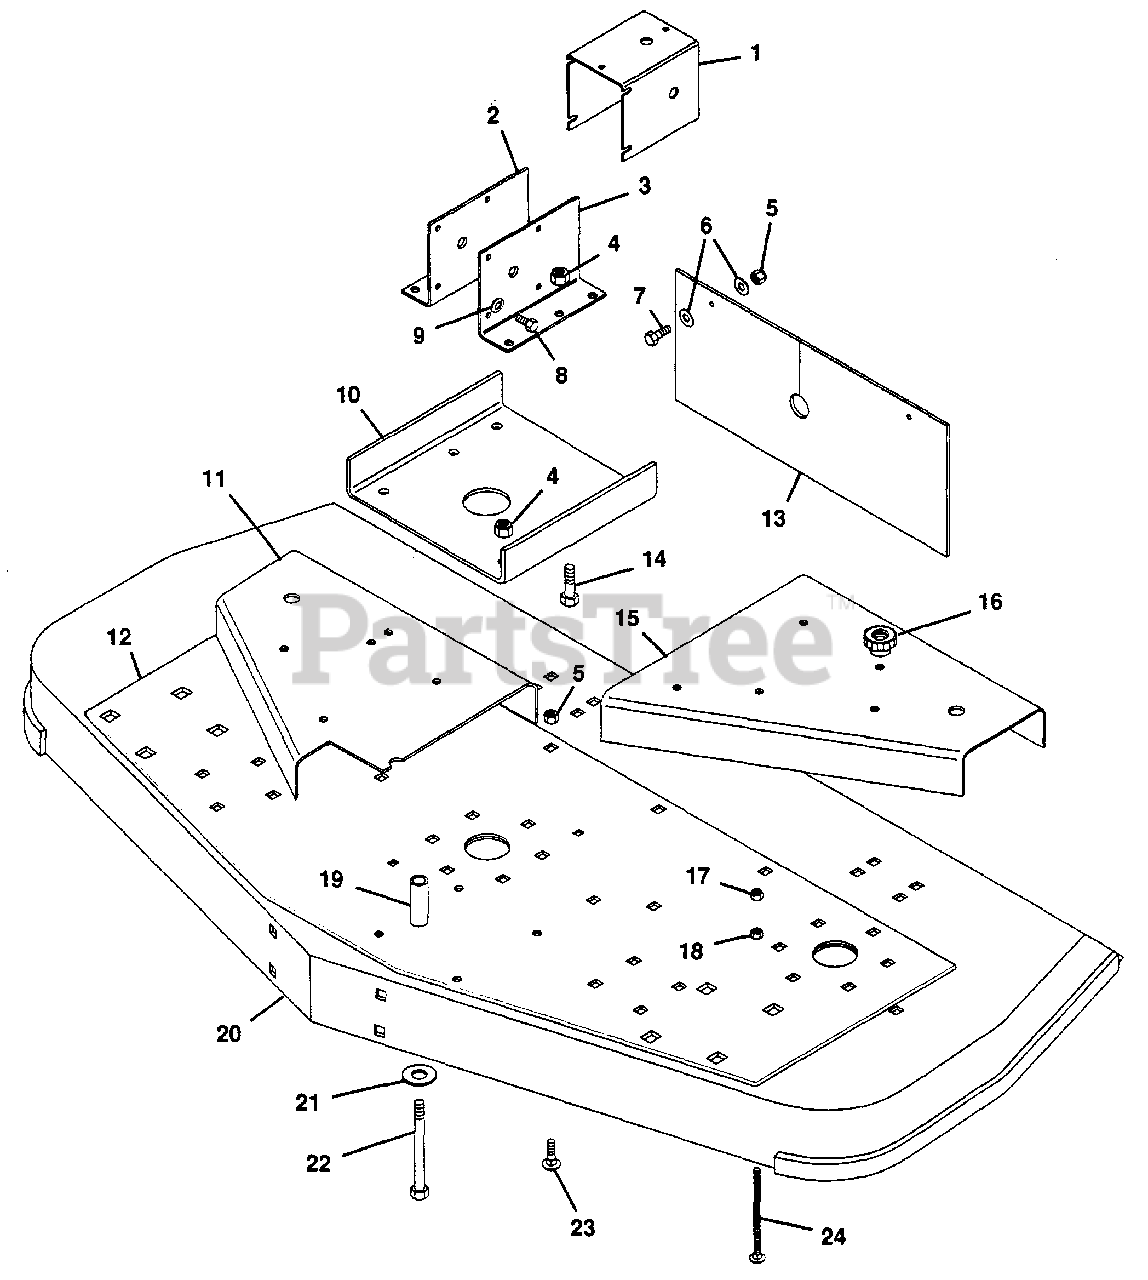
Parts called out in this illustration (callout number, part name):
1	Shield, U-Joint
2	Bracket, Gearbox Mounting R.H.
3	Bracket, Gearbox Mounting L.H.
4	Nut, Lock 1/2-13
5	Nut, Lock 3/8-16
6	Washer, Flat .406x.812x.065
7	Bolt, Hex 3/8-16x1.00
8	Bolt, Hex 3/8-16x.875
9	Washer, Lock 3/8 Reg.
10	Plate, Support
11	Cover, Belt R.H.
12	Plate, Deck Support
13	Shield, Grass
14	Bolt, Hex 1/2-13x1.00
15	Silkscreen, Belt Cover
16	Knob
17	Nut, Lock 5/16-18
18	Nut, Jam 5/16-18 Hex
19	Bushing, St. .562x1.00x2.00 Stl.
20	Weldment, 72" R.D. Deck
21	Washer, Flat .531x1.062x.095
22	Bolt, Hex 1/2-13x3.75
23	Bolt, 3/8-16x1.00 Rd Hd Sq Nk
24	Bolt, 5/16-16x4.0 Rd Hd Sq Nk
